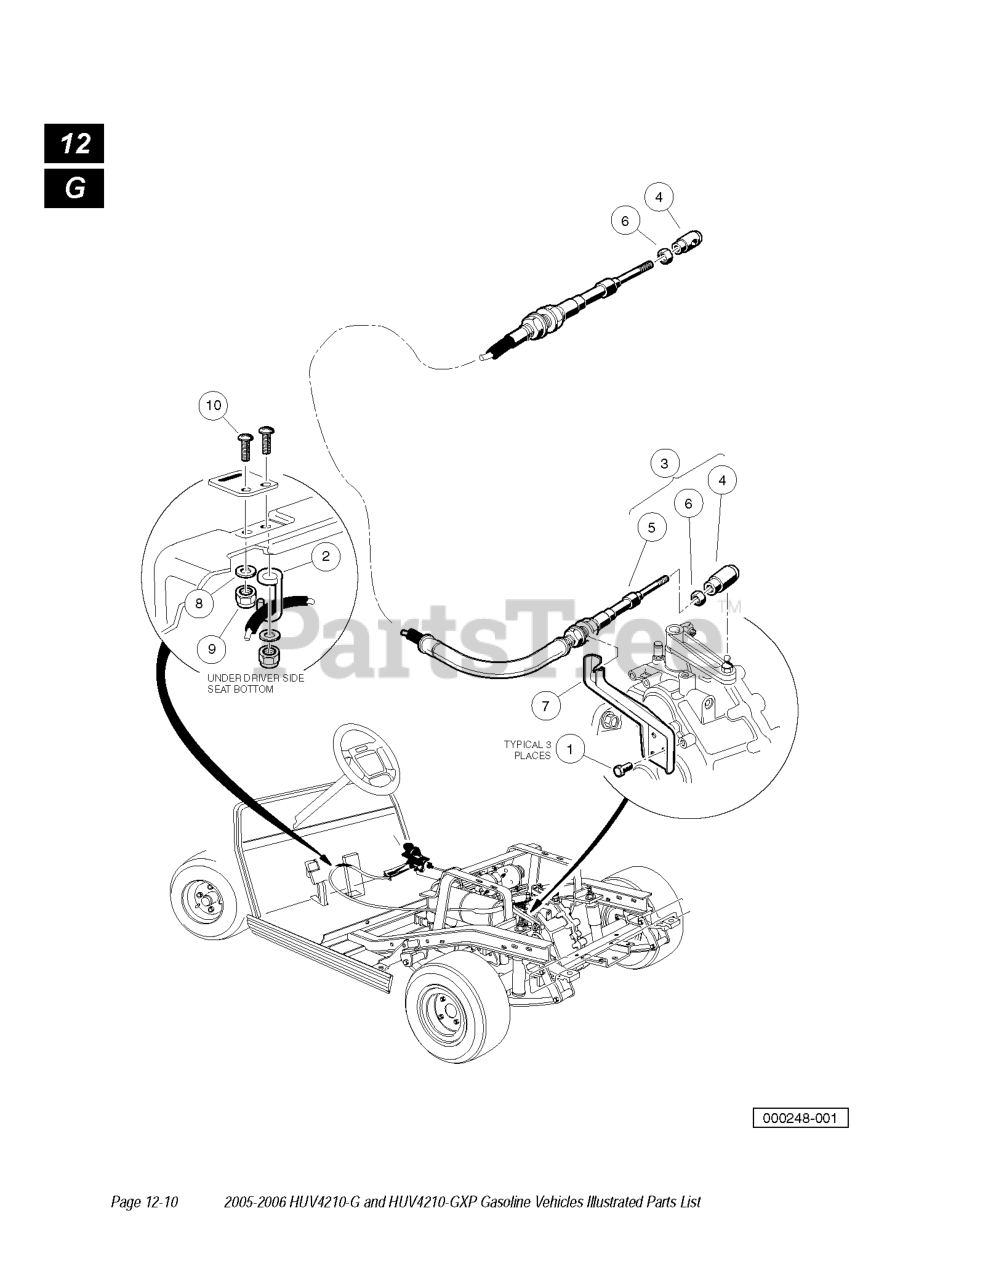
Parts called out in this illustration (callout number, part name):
1	SCREW HX TYP TT
2	CABLE RETAINER
3	TRANS CABLE W/BALL JOINTS
4	JOINT, #10-32 BALL
6	NUT, #10-32 HEX
7	SHIFTER BRACKET
8	WASHER 1/4 FLAT
9	LOCKNUT, 1/4-20 NYLON INSERT
10	SCREW, 1/4-20 X 1.0 TRS HD MCH
